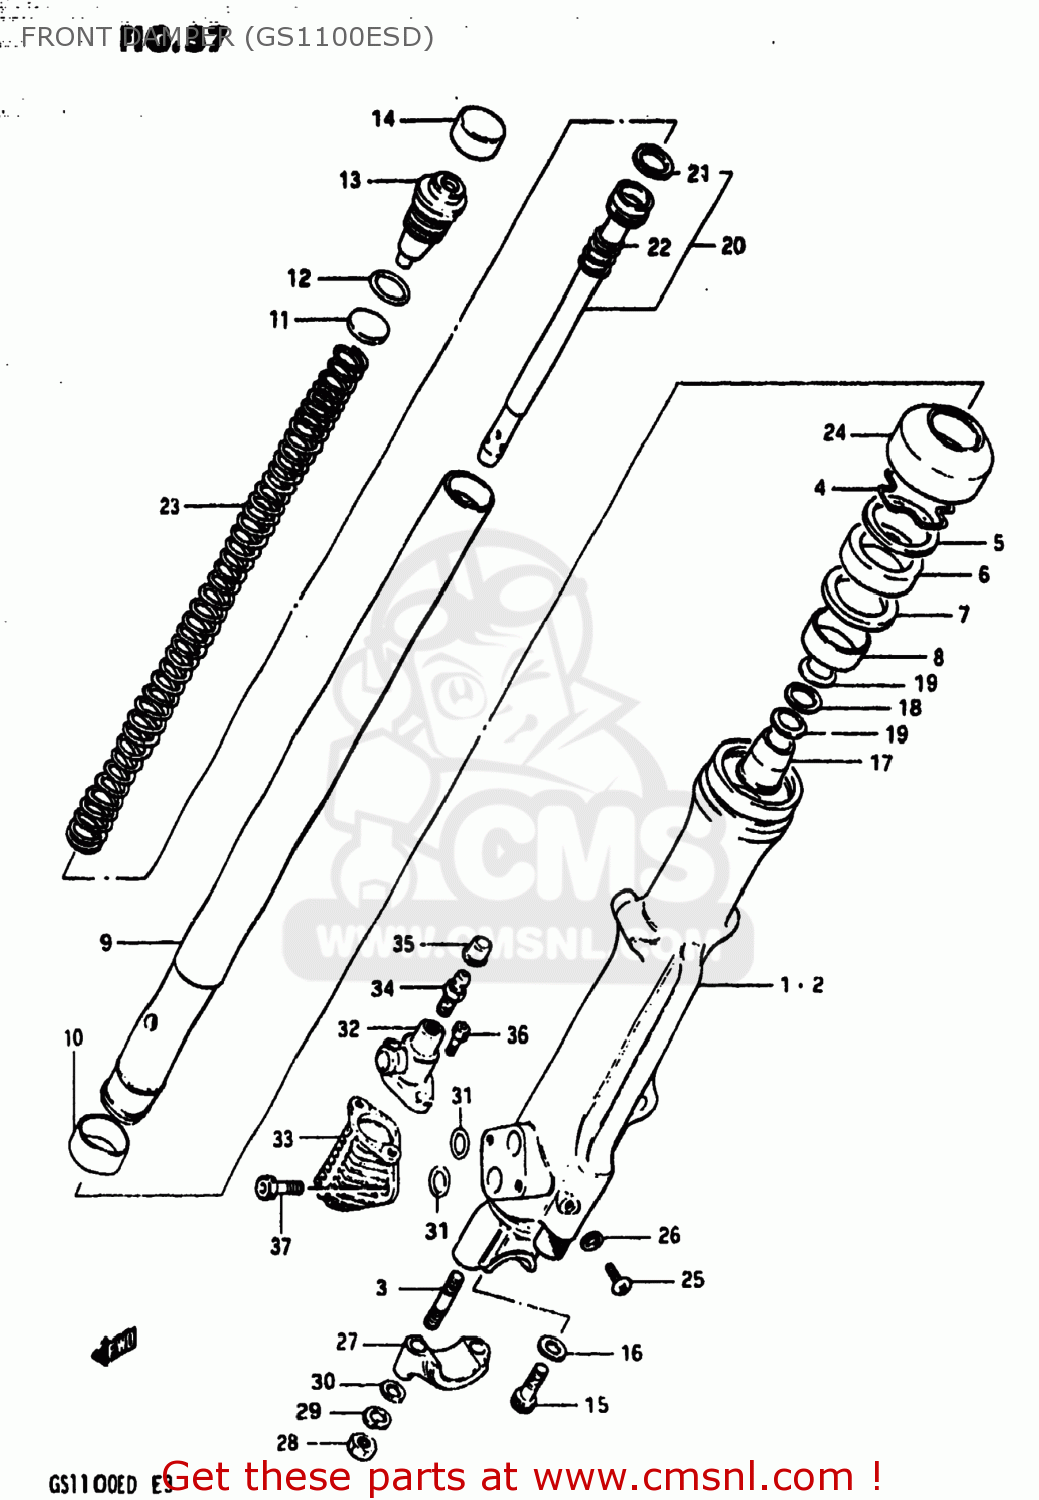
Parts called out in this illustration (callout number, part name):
0	DAMPER ASSEMBLY,LEFT
1	TUBE,FORK,OUTER,RIGHT
2	TUBE,OUTER,LEFT
3	STUD 8X30
4	RING,STOPPER
5	WASHER. FRONT FORK
6	OIL SEAL,FRONT FORK
7	WASHER
8	METAL,SLIDE
9	TUBE,FORK,INNER
10	METAL,FRONT FORK PISTON
11	WASHER
12	O RING
13	CAP
14	CAP,RUBBER
15	BOLT,FORK CYLINDER(10X25)
16	GASKET (NAS)
17	PIECE,OIL LOCK
18	WASHER
19	SPRING,LEAF
20	CYLINDER,FRONT FORK
21	RING,PISTON
22	SPRING,FORK REBOUND
23	SPRING,FRONT FORK
24	SEAL,DUST
25	SCREW
26	GASKET,DRAIN,PLUG (NAS)
27	HOLDER,AXLE
28	NUT
29	LOCK WASHER
30	WASHER
31	O RING
32	PLANGER SET,MODULATOR
33	VALVE SET,MODULATOR
34	BREATHER,AIR
35	CAP,BREADER
36	BOLT, MODULATOR (5X12)
37	BOLT,FRONT FORK
